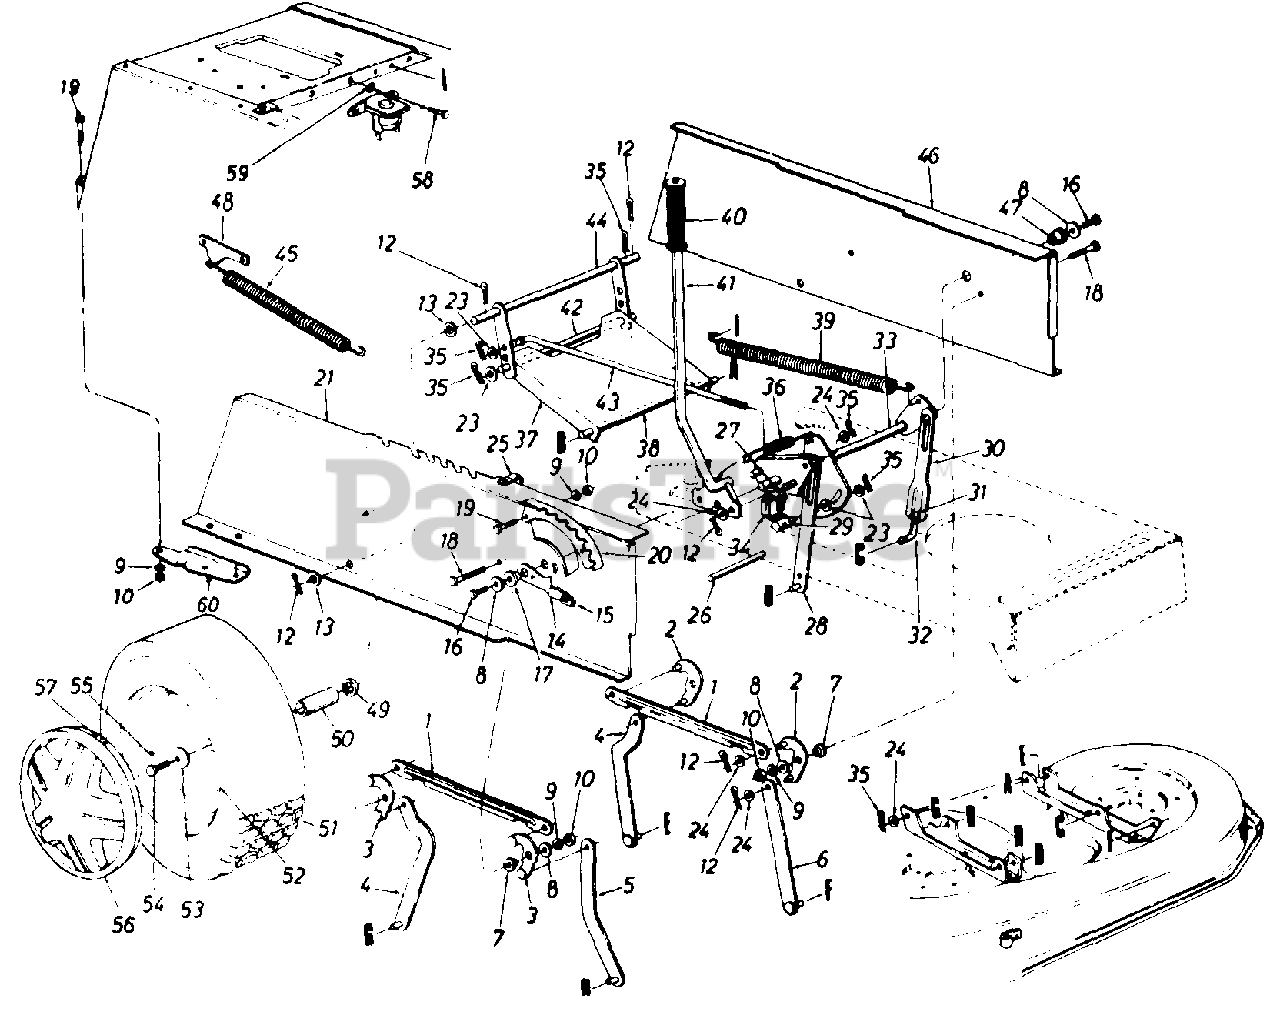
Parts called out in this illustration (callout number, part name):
1	Connecting Rod
2	Pivot Link Ass'y. - L.H.
3	Pivot Link Ass'y. - R.H.
7	Shld. Spacer .318" I.D.
8	Fl-Wash. .344" I.D. x .62" O.D.
9	L-Wash. 5/16" I.D.
10	Hex Nut 5/16-18 Thd.
12	Cotter Pin 1/8" Dia.
13	Fl-Wash. .635" I.D. x 1.0" O.D.
14	Deck Lift Stop
16	Hex TT-Tap Scr. 5/16-18 x .75"
17	Flange Brg. .63" I.D.
18	Hex Wash. Hd. Scr. 5/16-18 x .875"
19	Hex Bolt 5/16-18 x .75" Lg.
20	Index Brkt.
21	Upper Frame - R.H.
23	Fl-Wash. .385" I.D. x .87" O.D.
24	Fl-Wash. .531" I.D. x .93" O.D.
26	Running Board Rod
27	Hex Tap Scr. #12 x .375"
31	Hex Nut 1/2-20 Thd. (Gr. 5)
32	Lift Link Adjuster
35	Inter. Cotter Pin 3/8" Dia.
36	Extension Spring
37	Stabilizer Bracket
38	Shaft 1/2" Dia. x 10.28" Lg.
39	Extension Spring
40	Grip (Lift Handle)
41	Deck Lift Handle Ass'y.
42	Weld Pin
43	Disengagement Rod
44	Stabilizer Shaft Ass'y.
45	Extension Spring
46	Upper Frame - L.H.
47	Flange Brg. .632" I.D.
48	Deck Spring Brkt.
49	Fl-Wash. .76" I.D. x 1.49" O.D.
50	Sleeve .75" I.D. x 1.0" O.D.
52	Wheel Rim Only
53	Bell-Wash. .345" I.D. x .88"
54	Hex L-Bolt 5/16-24 x .75" Lg.
55	Air Valve
57	Spring Clip
58	Hex Wash. Hd. TT-Tap Scr. 1/4-20 Thd.
59	Ext. L-Wash. 1/4" I.D.
